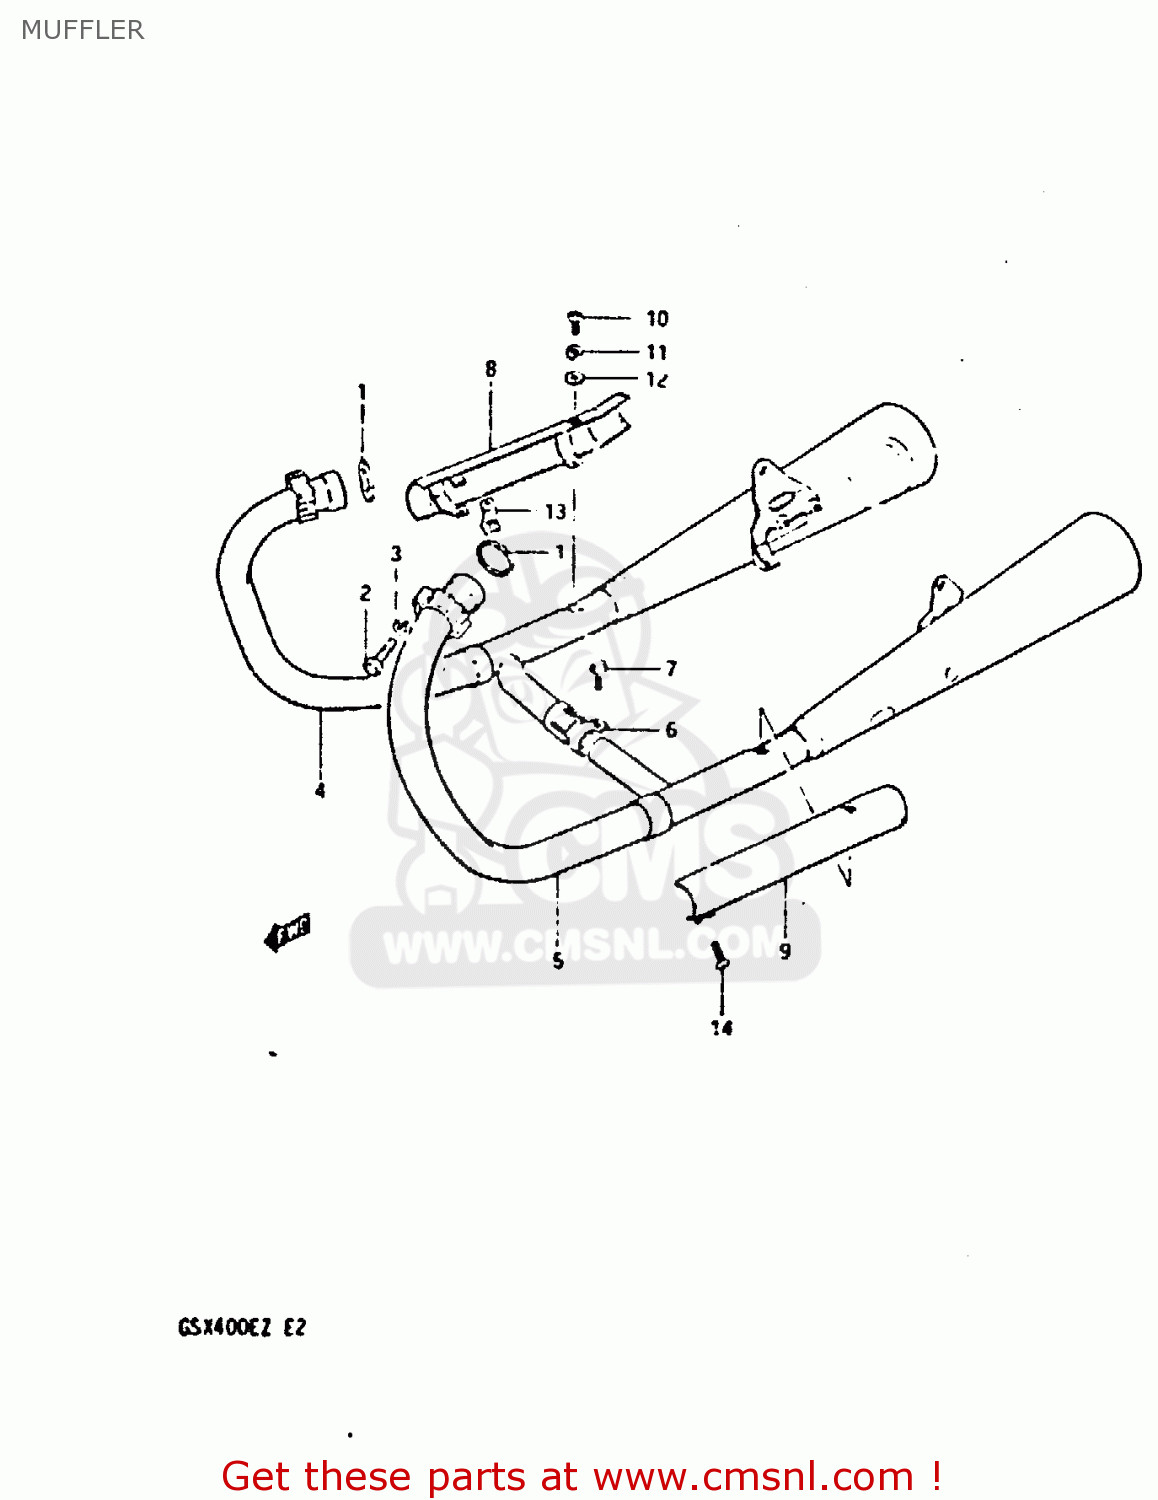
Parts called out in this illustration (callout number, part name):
1	GASKET,EXHAUST PIPE (NAS)
2	BOLT 8X40
3	LOCK WASHER
4	MUFFLER, RH
5	MUFFLER, LH
6	CLAMP
7	BOLT
8	COVER, MUFFLER RH
9	COVER, MUFFLER LH
10	SCREW
11	LOCK WASHER
12	WASHER
13	CLAMP,MUFFLER COVER
14	SCREW
